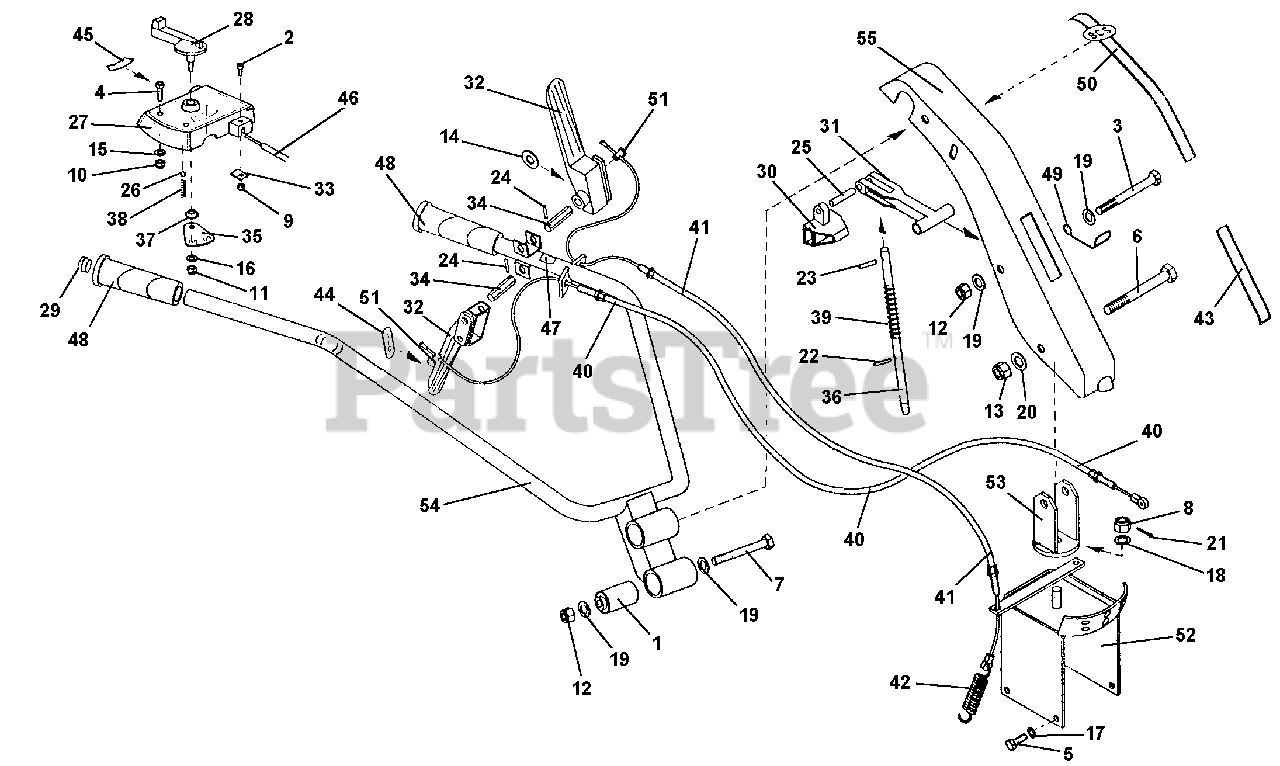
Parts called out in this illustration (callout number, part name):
1	SILENT BLOCK
2	SCREW M5X10
3	SCREW M10X85
4	SCREW M6X35
5	SCREW M8X20
6	SCREW M12X85
7	SCREW M10X80
8	NUT, SELF LOCKING M12
10	NUT, SELF LOCKING M6
11	NUT, SELF LOCKING M8
12	NUT, SELF LOCKING M10
13	NUT, SELF LOCKING M12
15	WASHER, FLAT M6.3
16	WASHER, FLAT M8.4
17	WASHER M8.4
19	WASHER, LOCK M10.5
20	WASHER, LOCK M13
22	LOCKING PIN M3X18
23	LOCKING PIN M4X35
24	LOCKING PIN M4X25
25	LOCKING PIN M8X50
27	THROTTLE CONTROL COVER
28	THROTTLE LEVER
30	SUPPORT, ROD
31	ADJUSTING LEVER
34	PIN, HEXAGONAL
35	QUADRANT, THROTTLE CONTROL
36	HANDLEBAR POSTIONING ROD
37	SPRING WASHER
38	SPRING, THROTTLE CONTROL
39	SPRING, ROD
40	CABLE ASSEMBLY, PTO
41	CABLE ASSEMBLY, DRIVE
42	SPRING WHEEL DRIVE
45	DECAL, THROTTLE
46	THROTTLE CABLE
47	DECAL, WHEELS
48	COVER, HANDLEBAR
49	CABLE GUIDE
50	DECAL "CRUSADER"
52	HANDLE COLUMN ANCHOR
53	HANDLE COLUMN SUPPORT
55	HANDLEBAR COLUMN
